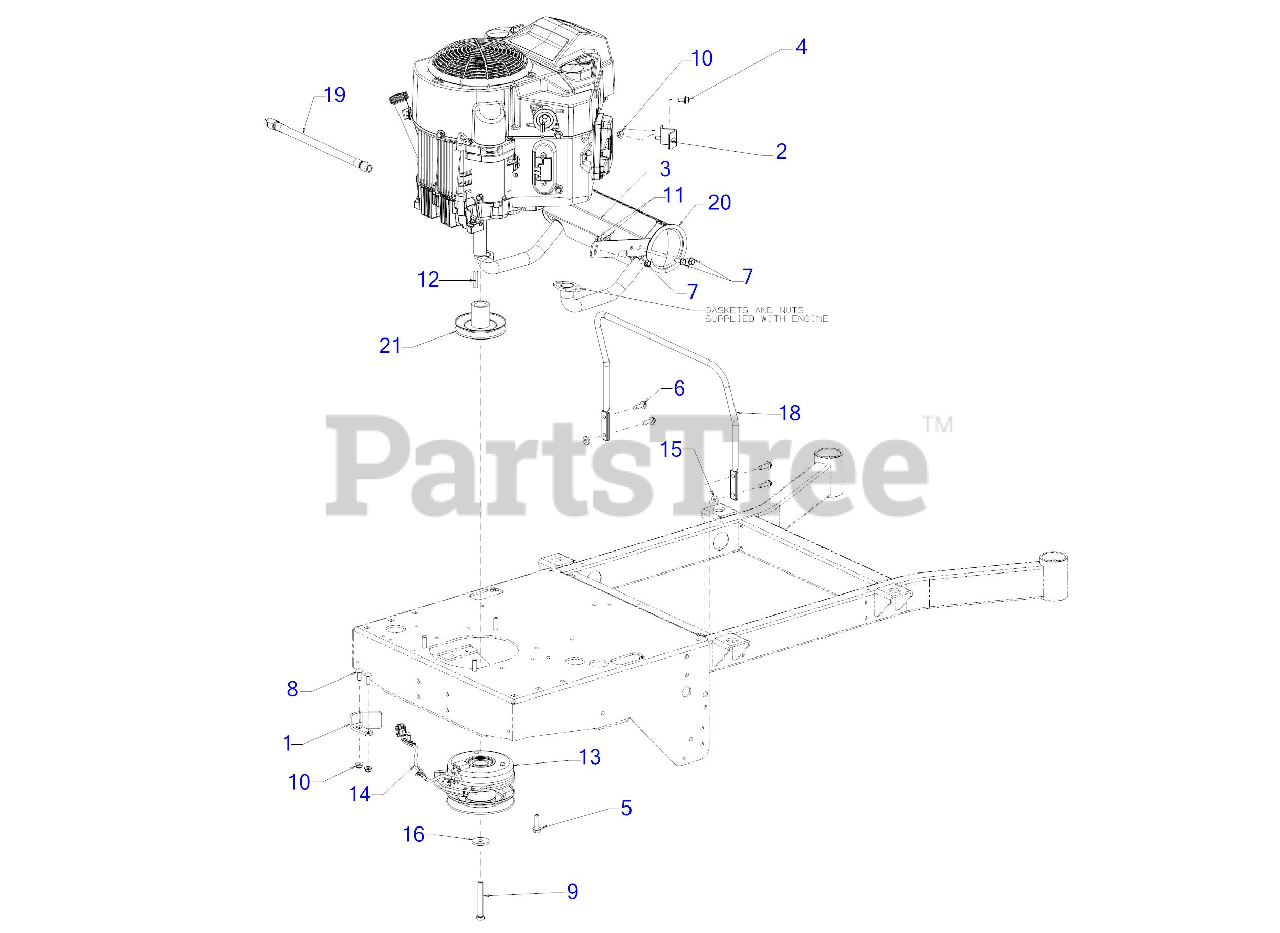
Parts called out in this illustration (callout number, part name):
1	PTO CLUTCH RETAINER BRACKET
2	MUFFLER MOUNTING BRACKET
3	MUFFLER SHIELD
4	SCREW M8 x 1.25 x 16MM GR8.8
5	SCREW 3/8-16 x 1.25 GR5
6	SCREW 5/16-18 x 1.00
7	SCREW 5/16-18 x .750 GR8
8	BOLT 5/16-18X .875 GR1
9	SCREW 7/16-20 x 3.25 GR5
10	FLANGE LOCK NUT 5/16-18
11	FLANGE NUT
12	SQUARE KEY 1/4 x 1.50
13	PTO CLUTCH
14	CLUTCH HARNESS 11"
15	FLAT WASHER
16	FLAT WASHER .45 x 1.5 x .172 HT
18	MUFFLER ROD
19	OIL DRAIN HOSE
20	MUFFLER (ROUND)
21	ENGINE PULLEY 1.125"
